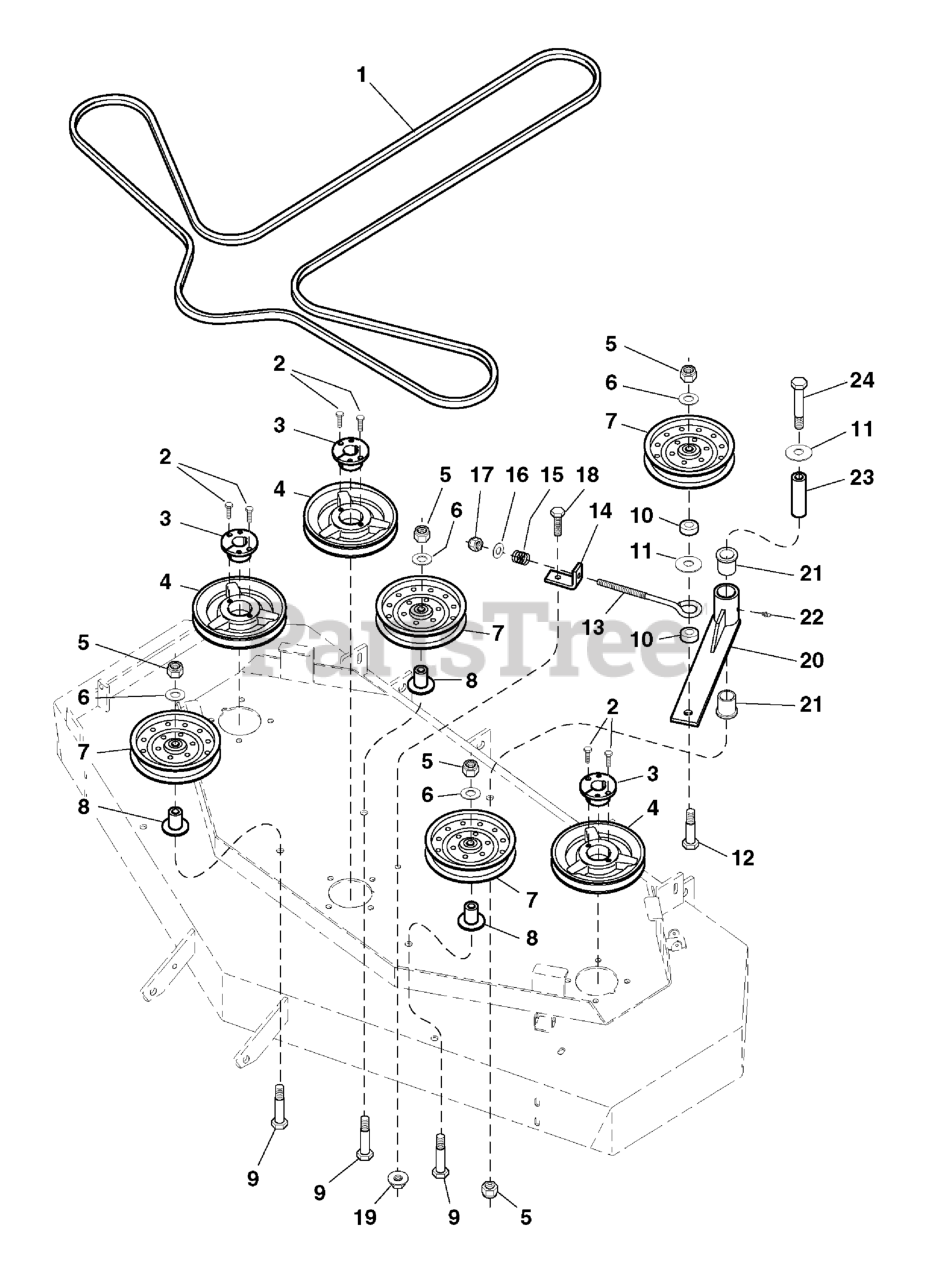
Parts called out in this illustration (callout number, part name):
1	BELT, 5V, 175.90EL, LG ARAMID, WRPD, RC
2	BOLT, 1/4-20 X 1" GD5 CZ
3	BUSHING, Tapered Hub
4	PULLEY, Spindle
5	NUT, 1/2-13 HEX NYLON LOCK
6	WASHER, 1/2 SAE
8	IDLER PULLEY MOUNT
9	BOLT, 1/2-13 X 3-1/2, HEX HD, GD5, CZ (SV)
10	SPACER, .52 x 1.00 x .44
11	WASHER, 1/2" USS
12	BOLT, 1/2-13 X 3" GD5 CZ
13	EYEBOLT, 3/8" x 8"
14	SPRING ANCHOR
15	SPRING, Compression
16	WASHER, 3/8 SAE
17	NUT, 3/8-16 HEX NYLON LOCK
18	BOLT, 3/8-16 X 1" GD5 CZ
19	NUT, 3/8-16 Hex Serrated Flange
20	IDLER ARM
21	BUSHING, FLANGE
22	GREASE FITTING
23	SPACER, .52 x 1.00 x 3.50
24	BOLT, 1/2-13 x 4-1/2
